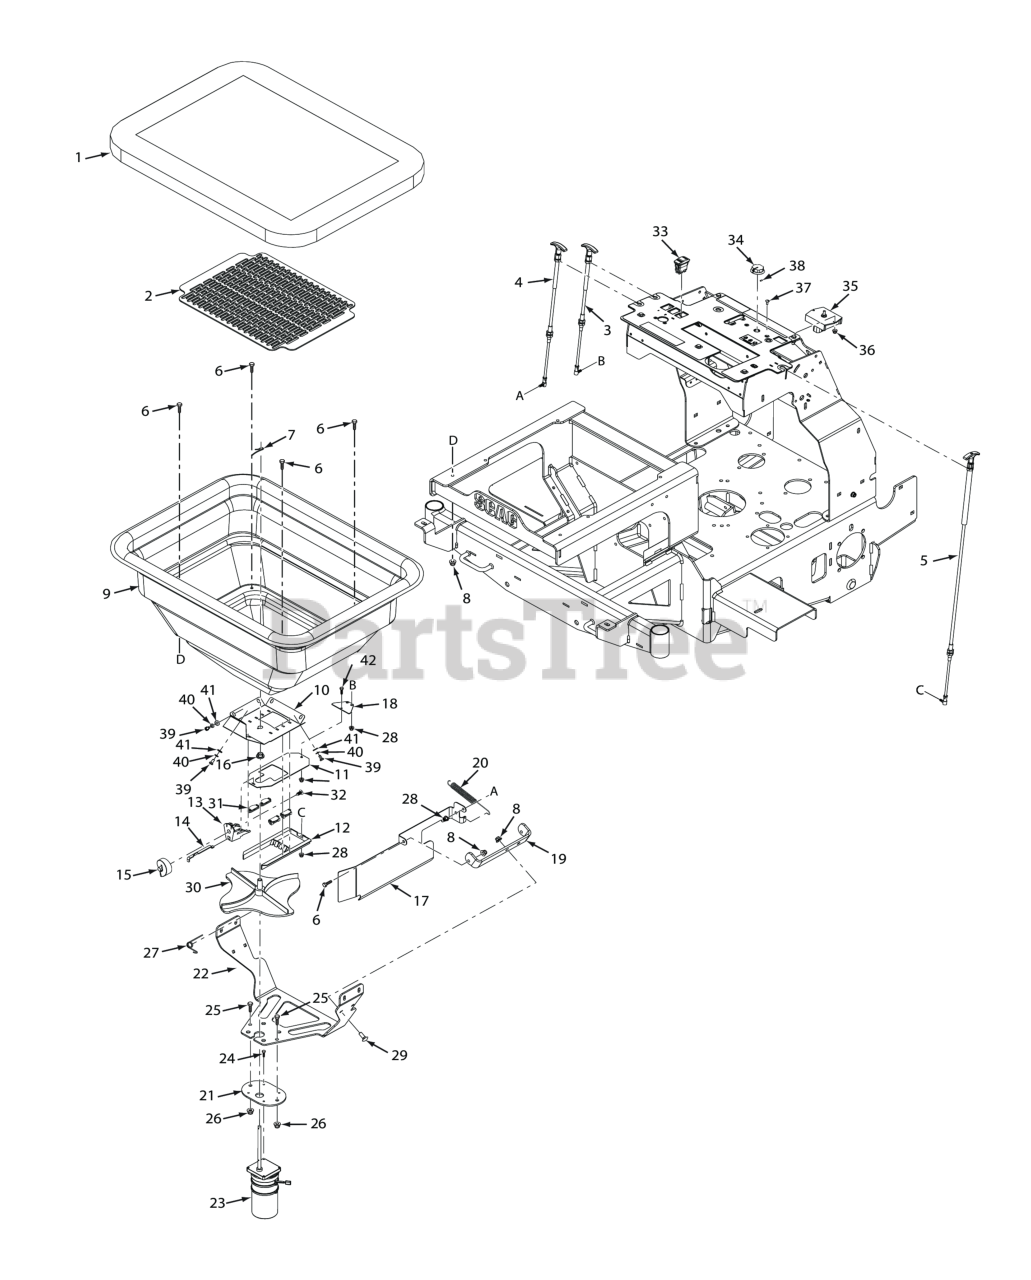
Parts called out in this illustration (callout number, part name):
1	Cover, 220lb Hopper
2	Grate, Spreader
3	Cable, Hopper Gate
4	Cable, Side Deflector
5	Cable, Pattern Adjust
6	Bolt, Hex 5/16" - .375 x 1.00- Stainless Steel
7	Agitator
8	Locknut, 5/16-18 Flg. Elastic Stop - Stainless Steel
9	Hopper Assembly
10	Mounting Plate, Speader System
11	Gate, Rear
12	Diffuser
13	Mount, Dial
14	Linkage, Rate Gate
15	Milled Dial
16	Bearing, Hopper Bottom
17	Guard Door, LH Hopper
18	Door Arm
19	Mounting Bracket, Deflector Door
20	Spring, Door Assist
21	Mounting Plate, Electric Motor
22	Motor Mount Bracket
23	Gear Motor, Electric
24	Bolt, Hex #10-32 x .50 - Stainless Steel
25	Bolt, Hex 3/8 - 16 x 1.00 - Stainless Steel
26	Nut, Flange Elastic Stop 3/8 - 16 - Stainless Steel
27	Spring, SS Clip
28	Nut, 1/4-28 Elastis Stop - Stainless Steel
29	Bolt, Carriage 5/16 - 18 x 1" - - Stainless Steel
30	Impeller
31	Guide, Rate Gate
32	Linkage, Rate Gate
33	Switch, Rocker
34	Knob (Incl #38)
35	Motor Controller
36	Locknut, #10 - 32 Elastic Stop - Stainless Steel
37	Bolt, Carriage #10 - 32 x .50 - Stainless Steel
38	Set Screw, #8 - 32 x .375
39	Bolt, Hex Head 1/4 - 20 x .50 - Stainless Steel
40	Washer, Lock 1/4 Spring - Stainless Steel
41	Washer, Flat 1/4-.281X.625X.080 - Stainless Steel
42	Bolt, Hex Head #10 - 32 x 3/4" - Stainless Steel
